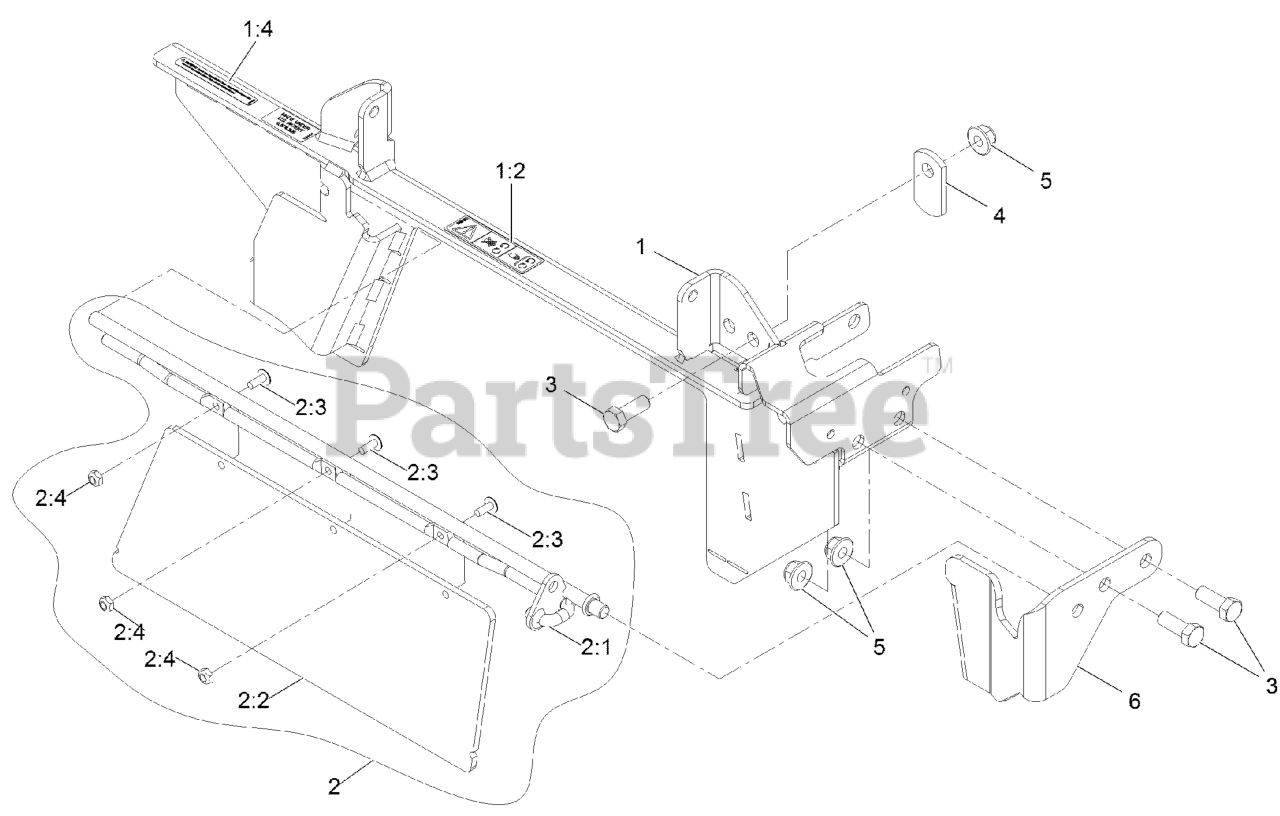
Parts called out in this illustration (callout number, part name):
1	OCD FRAME ASM W/ DECALS
1:2	DECAL, COVER MISSING
1:4	DECAL-WARNING
2	Ocd Gate ASM
2:1	GATE PIVOT ASM
2:2	GATE-OCD
2:3	SCREW-PTH
2:4	NUT-LOCK, NI
3	SCREW-HH
4	LATCH-CATCHER, GRASS
5	NUT-HF, NI
6	BRKT,CHUTE FRONT
